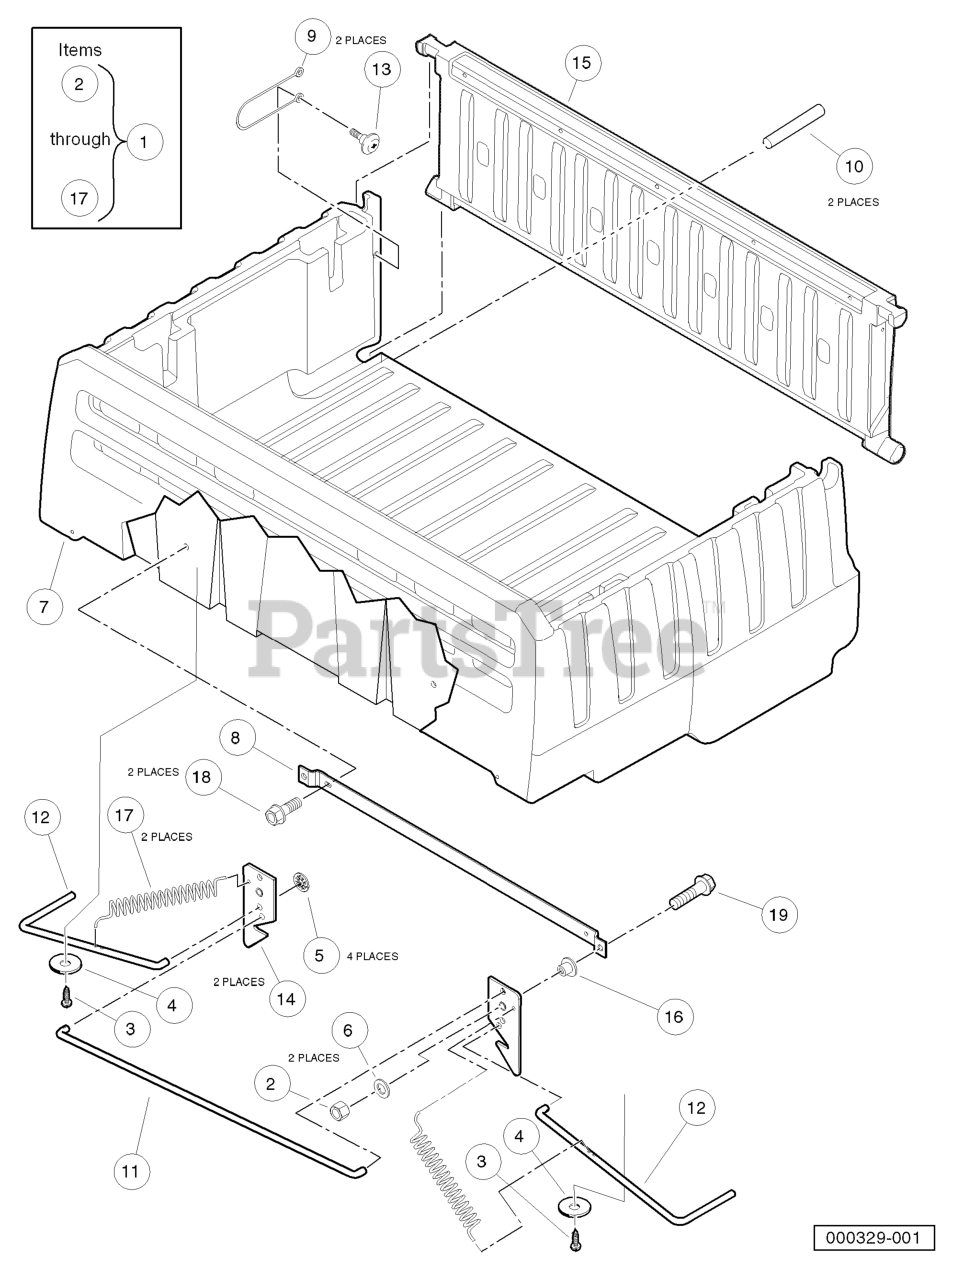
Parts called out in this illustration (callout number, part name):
1	BED ASM - 4200 SERIES
2	LOCKNUT, DIMPLED
3	SCREW, HEX WASH
4	WASHER, 5/16 TYPE B FLAT
5	PUSHNUT, 3/8
6	Washer, 3/8 Flat Type A
8	Support, Latch Link
9	LANYARD, TAILGATE
10	Pin, Support
11	Rod, Long Link
12	Rod, Bed Lift, Short Bent
13	BOLT LANYARD
14	Catch, Tilt Bed
15	TAILGATE, HUSQVARNA
16	Bearing, Bronze, 1/2x9/32
17	Spring, Tilt Latch 3.4 Lb/in
19	SCREW, CAP, HEX HD 3/8-16X1.00
